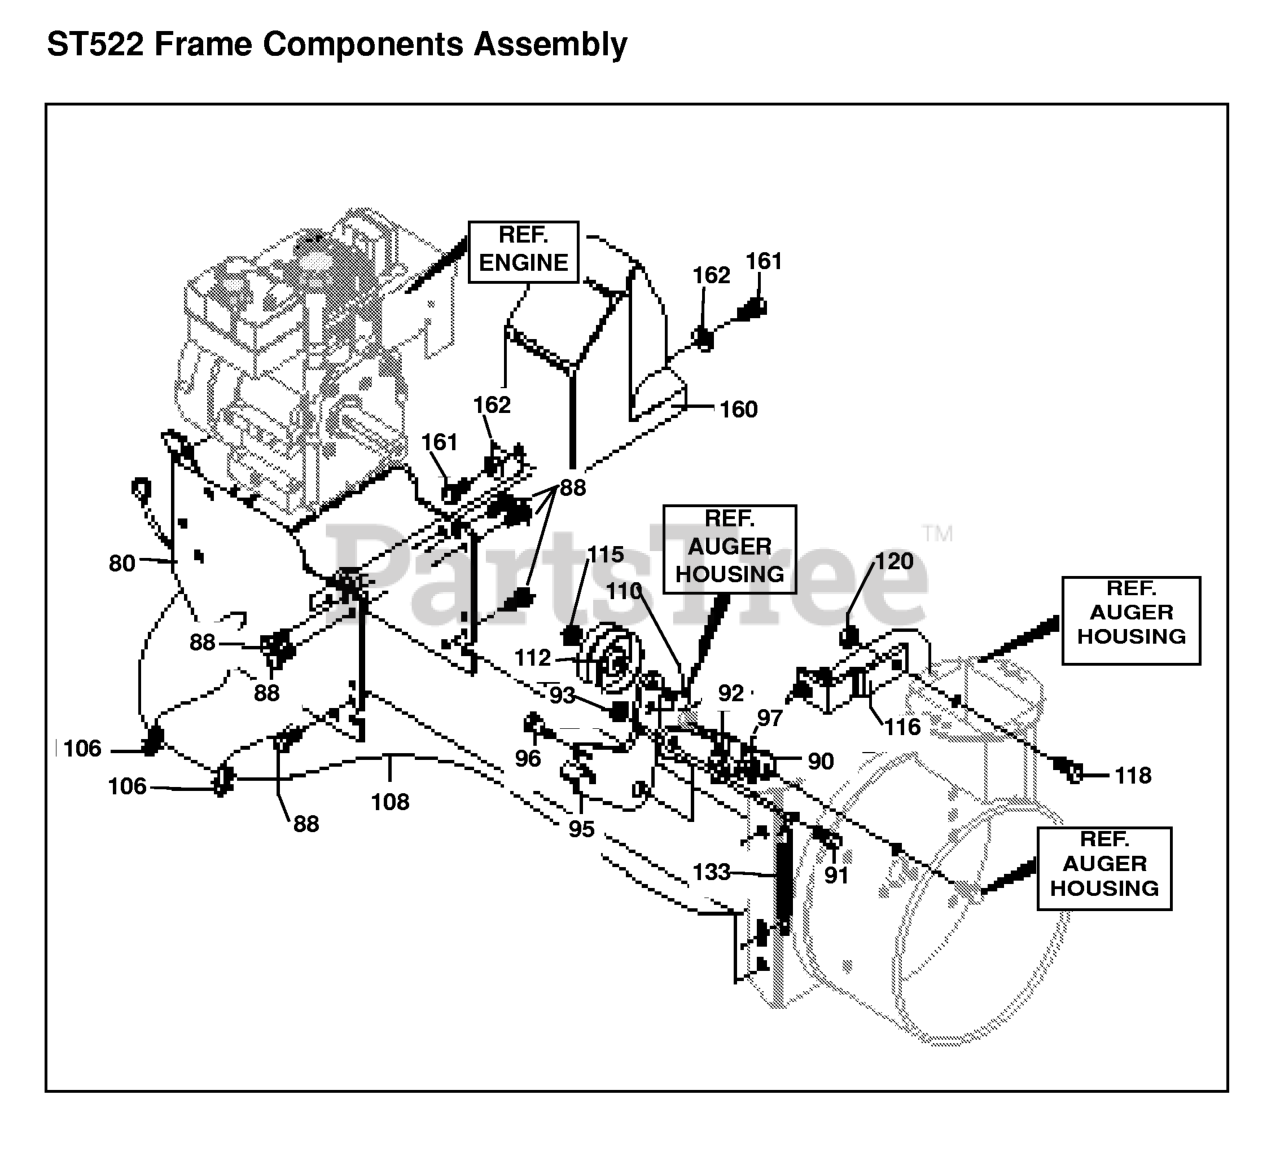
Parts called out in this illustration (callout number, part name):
80	FRAME ASSEMBLY
88	SCREW, 5/16-18X .75 WAHHT
90	PLATE, CLU. ARM MT
92	WASHER, REGSPTLK.393X.68X
93	NUT 3/8-16
95	ARM-CLUTCH CABLE
96	Bolt, .497 x .138 3/8-16
97	NUT, 3/8-16 REGHXCTRLK
106	CLIP, CABLE TINN
108	CABLE
110	SCREW, 3/8-16 X 1.25
112	IDLER PULLEY
116	Bracket, Compact Cable
118	Screw, 3/8-16 x 1.25
120	NUT, 3/8-16 REGHXCTRLK
160	COVER, BELT
162	WASHER, FLAT .281X .63X.
